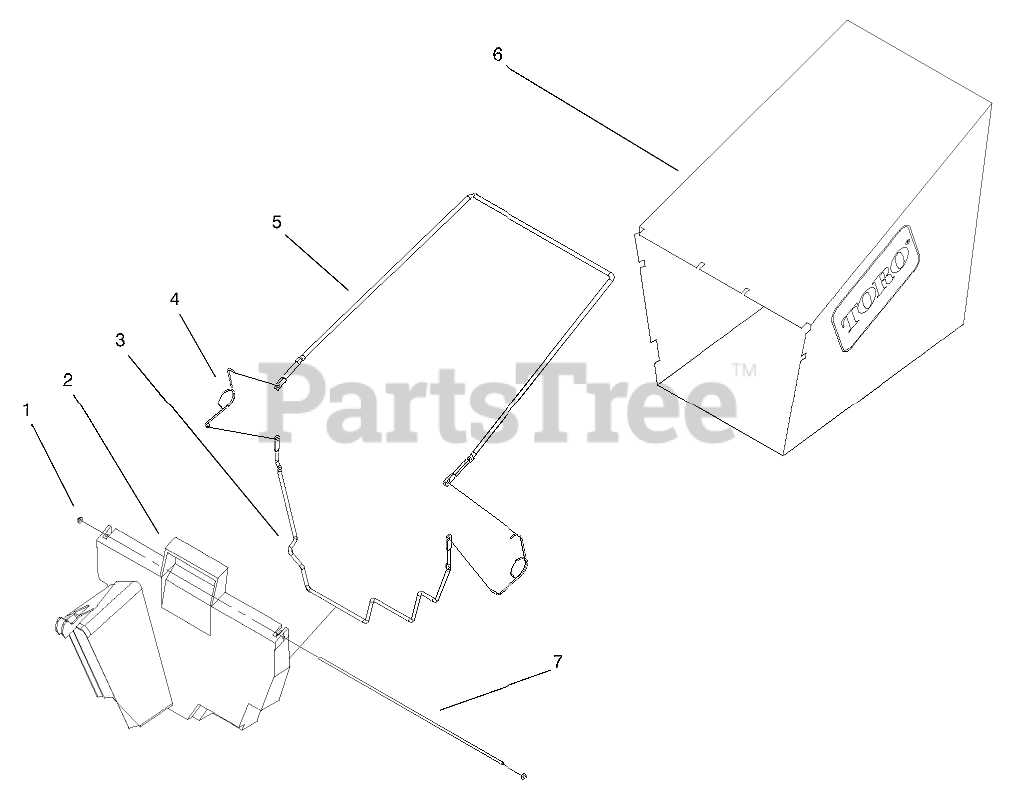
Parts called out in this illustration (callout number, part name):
1	NUT-PUSH
2	DOOR-BAG
3	FRAME-LOWER BAG
4	SPRING
5	FRAME-UPPER BAG
6	BAG-GRASS
7	HINGE-BAG DOOR
